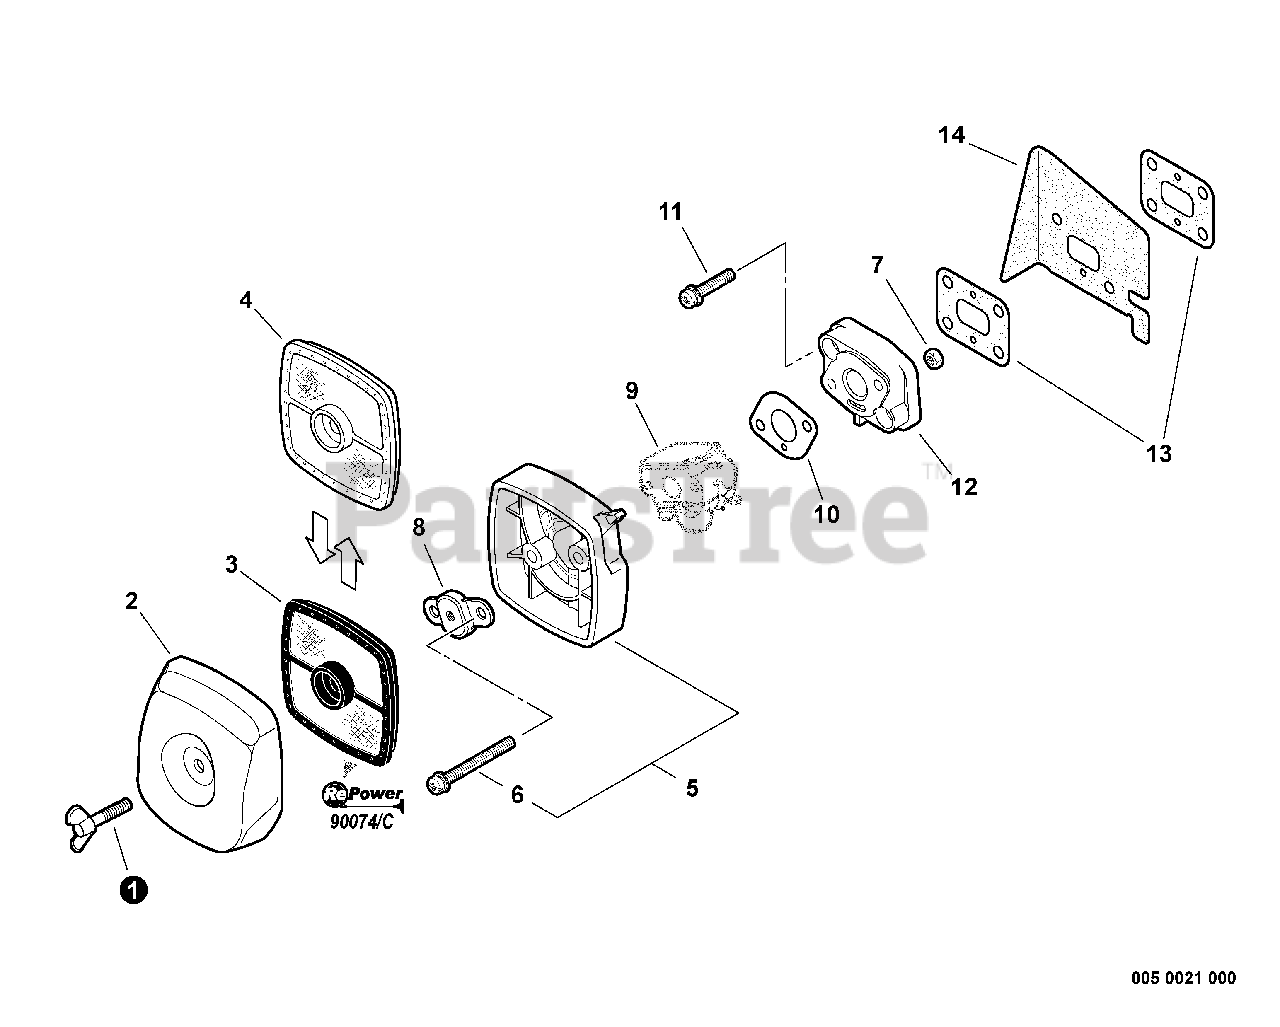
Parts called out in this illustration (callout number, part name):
1	BOLT, WING 5×20
2	COVER, AIR FILTER - GRAY
2	COVER, AIR FILTER - BLACK
3	FILTER, AIR - DOUBLE LAYER
4	FILTER, AIR - SINGLE LAYER
5	CASE, AIR FILTER - GRAY
5	CASE, AIR FILTER - BLACK
6	SCREW 5×65
7	NUT M5
8	PLATE, PREVENT
9	CARBURETOR
10	GASKET, INTAKE
11	SCREW 5×22
12	INSULATOR, INTAKE
13	GASKET, INTAKE
14	HEAT SHIELD, INTAKE
15	TUNE-UP KIT - REPOWER
